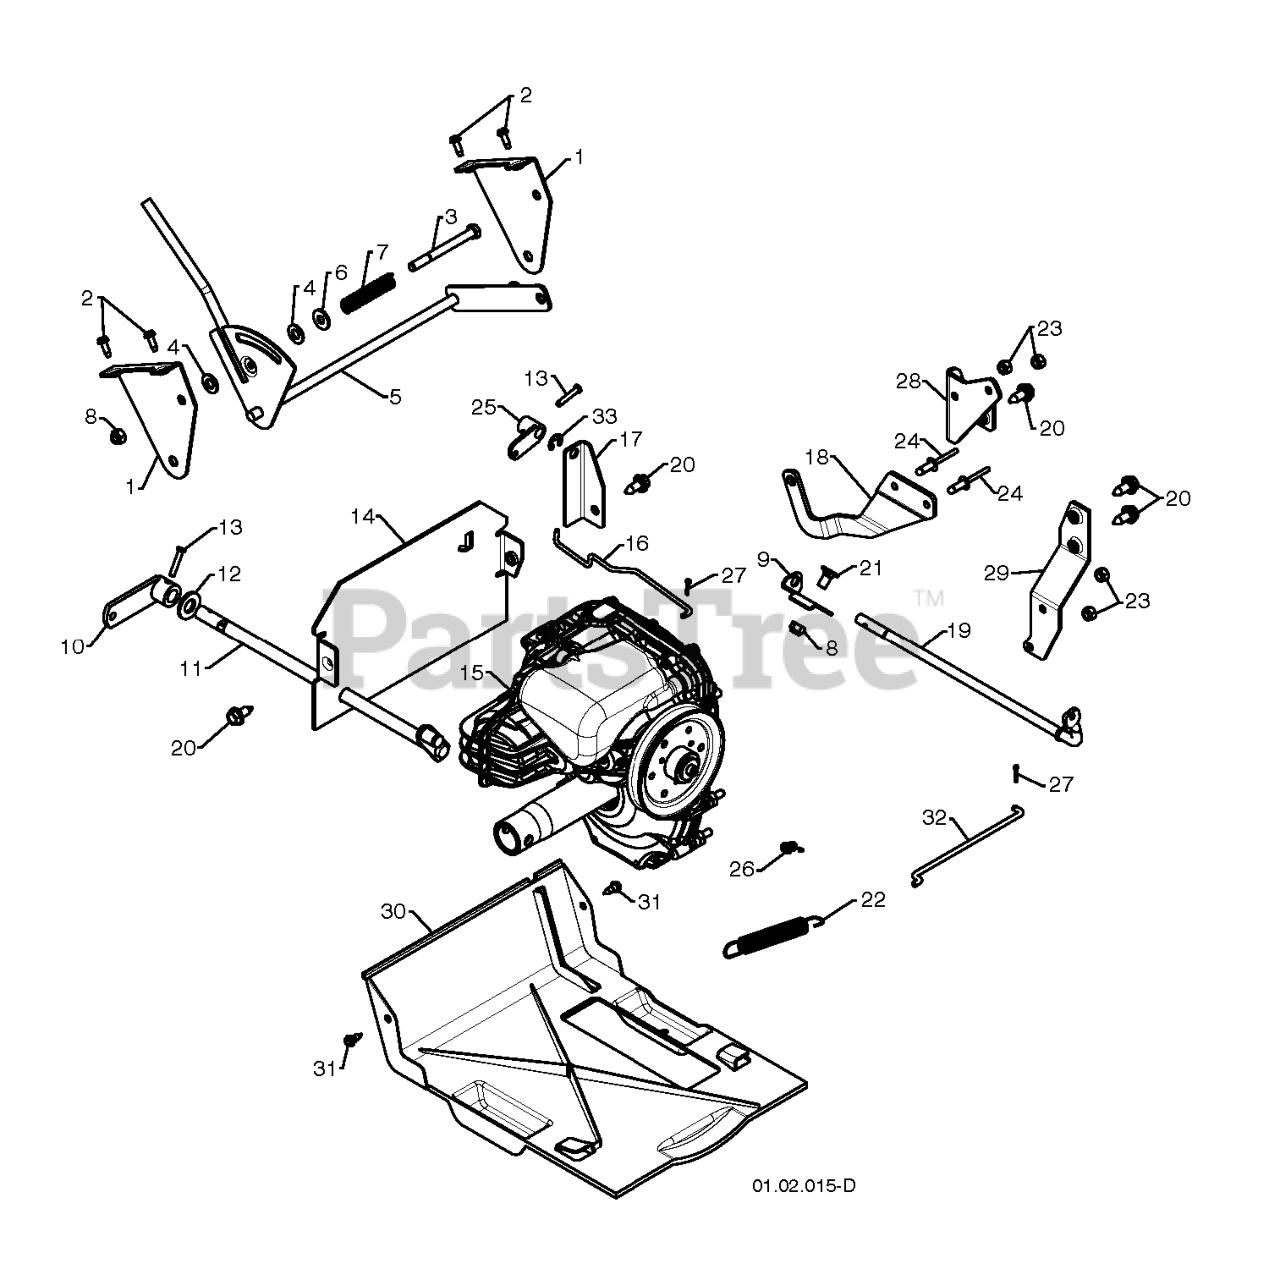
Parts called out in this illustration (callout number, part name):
1	BRACKET, SHIFT
2	SCREW #10-24 X 5/8
3	SCREW 5/16-18 X 3.25
4	WASHER, NYLON FRICTION
5	LEVER ASSEMBLY, SPEED CONTROL
6	WASHER.20X8.5
7	SRPING.FRICTION.HYDRO
8	NUT.71038.31-18.HEX.NYLOCK
10	ARM.CONTROL.AUGER
11	CONTROL.SHAFT.ASM
12	WASHER.FLAT.1/2
13	CLEVIS PIN
14	PLATE.REAR.HYDRO.ORANGE
15	TRANSMISSION.HYDRO.SNOW
16	ROD, BYPASS VALVE
18	ARM.CONTROL.HYDRO.SNOW
19	SHAFT.HYD.CLUTCH
20	BOLT.HEX.HD.WASHER.5/16-18X.75
21	BOLT.CARRIAGE.5/16-18X
22	SPRING, BRAKE
23	LOCKNUT.NYLOC.1/4-20
24	RIVET.POP.1/4X.475
25	ARM.HYD.CLUTCH
26	SPRING, TRACTION IDLER
27	RETAINER CLIP
28	BRACKET.ANTI-ROTATE.HYDRO.BLAC
29	STRAP.TORQUE.HYDRO
30	PAN.BOTTOM.PLASTIC
31	SCREW, HEX HEAD, TAPPING
32	RP ROD.HYD.CLUTCH
33	E-RING.RETAINER.REINFORCED.375
